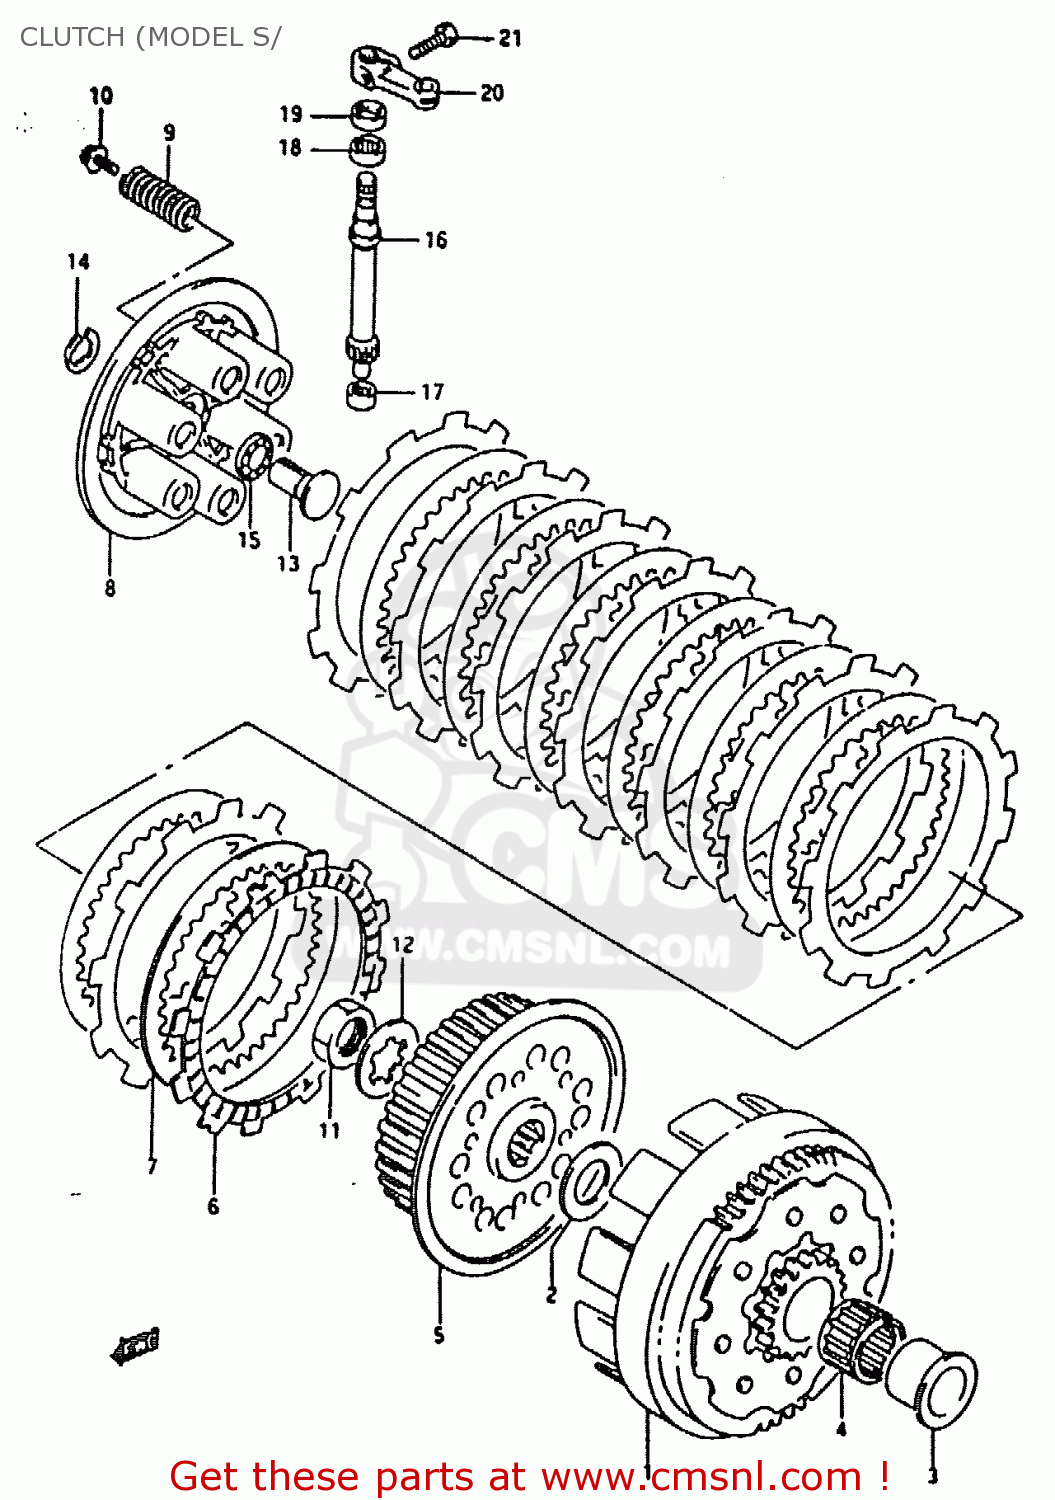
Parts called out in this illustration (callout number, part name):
1	GEAR ASSEMBLY,PRIMARY DRIVE
2	WASHER(22X38X2)
3	SPACER,PRIMARY DRIVEN GEAR
4	BEARING(29X34X21.8)
5	HUB,CLUTCH SLEEVE
6	PLATE,CLUTCH DRIVE (NAS)
7	PLATE,CLUTCH DRIVEN T: (NAS)
8	DISC,CLUTCH PRESSURE
9	SPRING
10	BOLT(5X25)
11	NUT
12	WASHER,LOCK
13	RACK,CLUTCH RELEASE
14	CIRCLIP,10MM
15	BEARING(10X22X2.8)
16	PINION,CLUTCH RELEASE(NT:12)
17	BEARING(9X13X10)
18	BEARING(12X16X10)
19	SEAL,OIL(10X17X5)
20	ARM,CLUTCH RELEASE
21	BOLT
